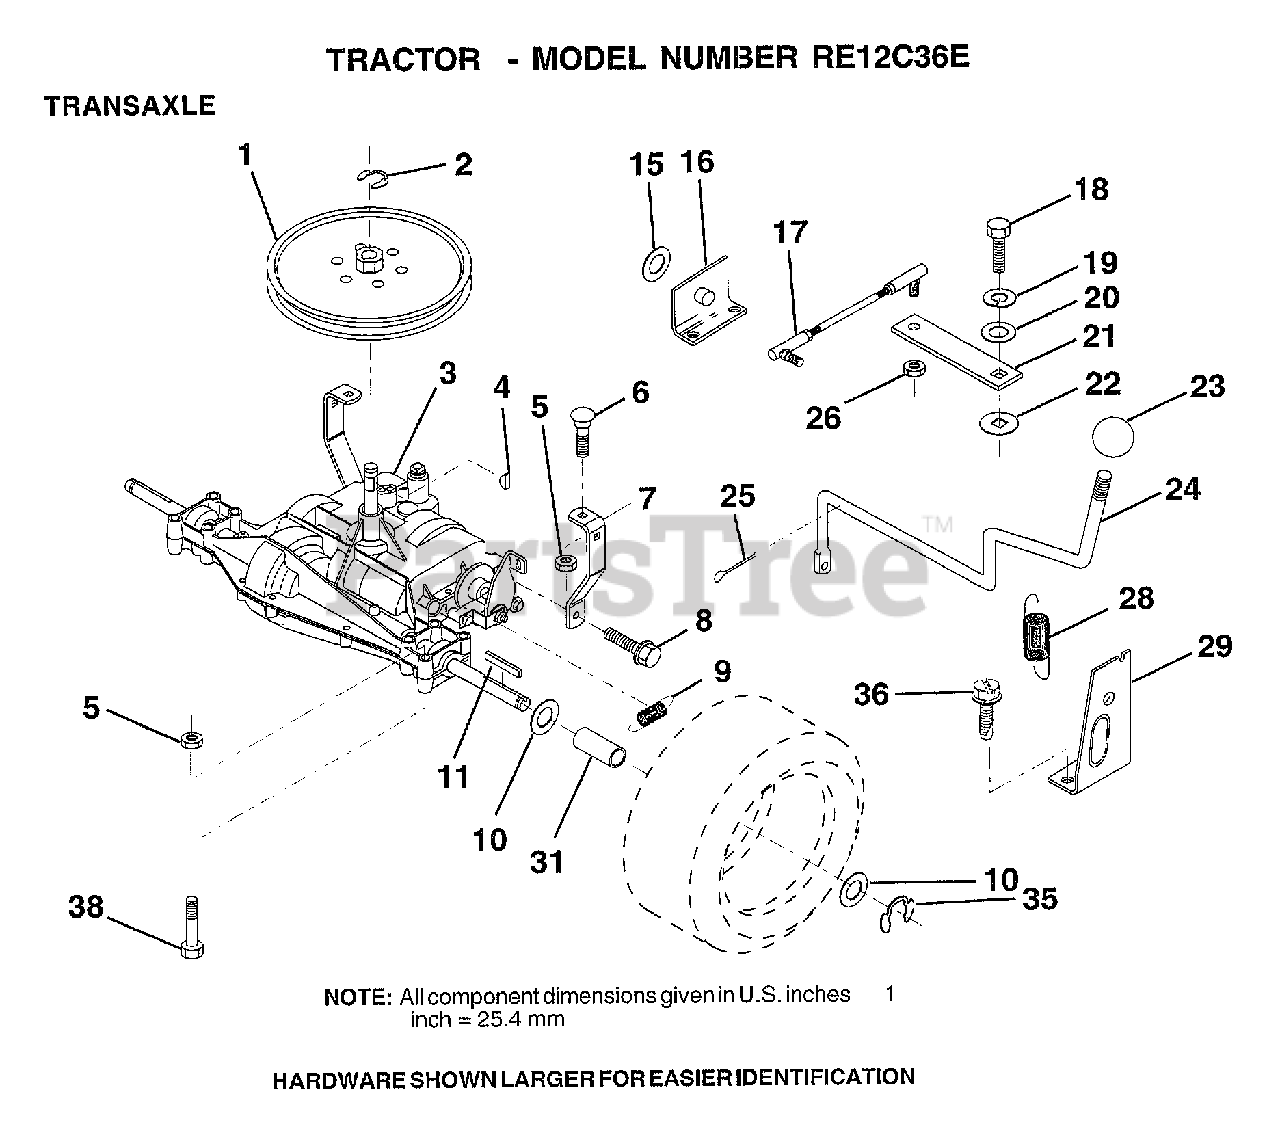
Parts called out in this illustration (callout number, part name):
1	PULLEY
6	BOLT
7	"STRAP,TORQUE"
8	SCREW
9	SPRING.BRAKE.RETU
10	WASHER
11	SQUARE KEY
16	"SUPT,HDLE SHT LH"
17	LINK SHIFT
18	BOLT.1/4-28.W/PAT
19	LOCKWASHER
20	WASHER LT
22	WASH-SHFT PLT LT
23	KNOB T (1/2-HOLE)
24	"ROD,SHIFT"
25	PIN COTTER 1/8
26	NUT.LOCK.5/16-24
28	"SPRING,EXT"
29	"SUPT,HDLE RH"
31	SPACER AXLE
35	E-RING LT
36	SCREW
38	BOLT.HEX.FLGHD
